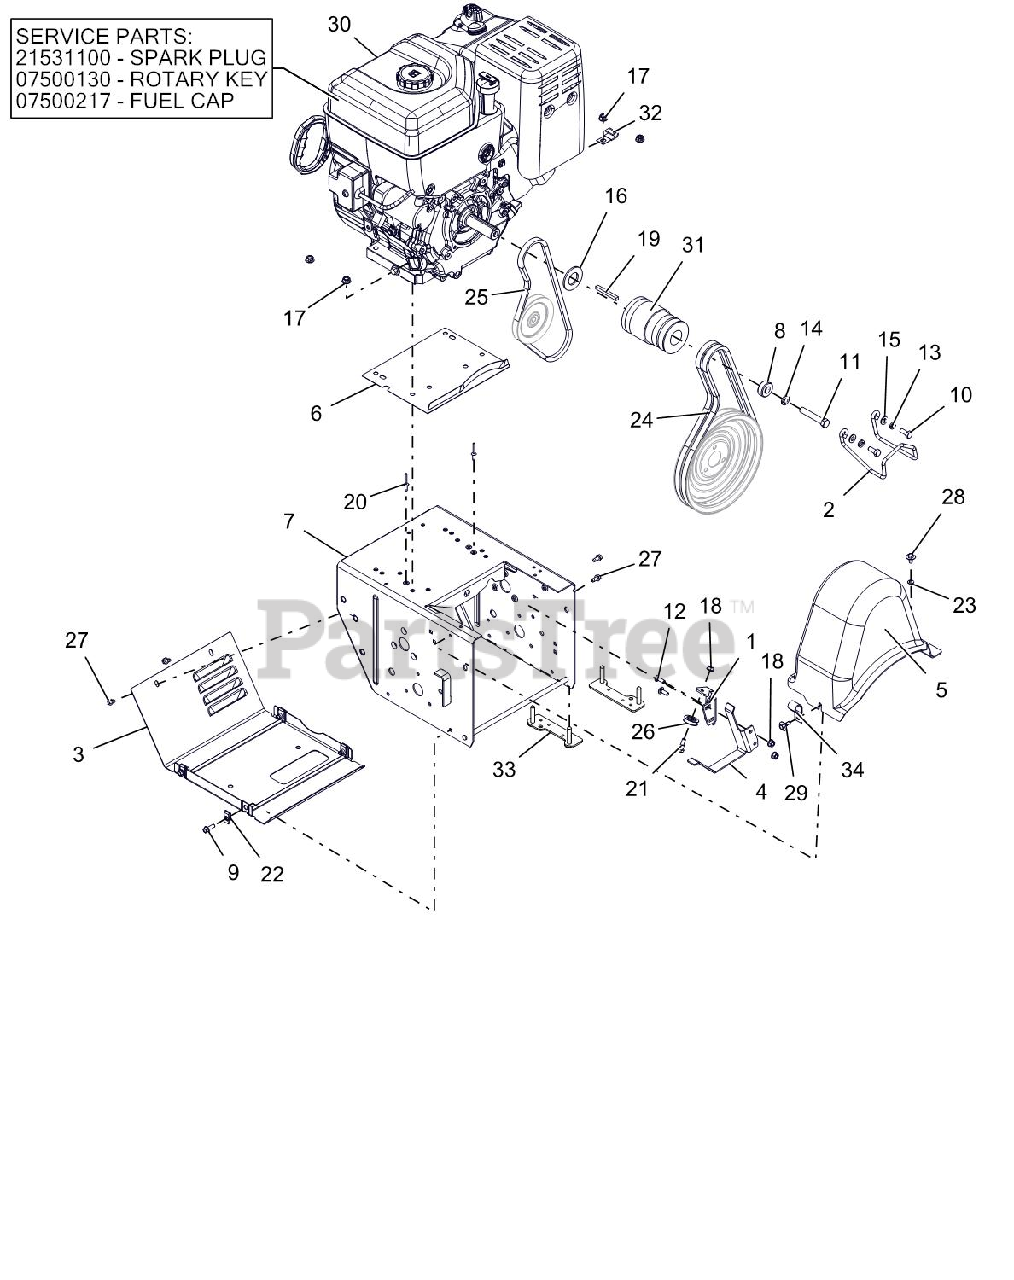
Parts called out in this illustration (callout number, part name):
1	BRACKET, CLUTCH CABLE
2	FINGER, BELT
3	COVER, BOTTOM - VENTILATED
4	FINGER, BELT - FLAT
5	COVER, BELT-LARGE
6	BAFFLE, WATER - LARGE BLOCK
7	FRAME, MAIN - PRO (WELDMENT)
8	BSHG-SPACER .47X1.25X.50
9	BLT-HEX .25-20X.75 HWH YZ GR5
10	BLT-HEX .31-24X.75 YWZC GR5
11	BLT-HEX .44-20X2.50 GR5 YWZC
12	@BLT-RDHDSQNK .25-20X.75 G5YZ
13	WSHR-LK .312X.097 HVY YWZC
14	@WSHR-LK .44X.109 REG YWZC
15	@WSHR-FL-STL.344X.688X.065YWZC
16	WSHR-FL-STL- 1.062X2.0X.134 YZ
17	@NUT-LK-CTR-FLG .31-18 YZ GR F
18	@NUT-LK-TOP-FLG .25-20 YWZC
19	KEY .25X.25X2.25
20	RVT-POP .187 YZ
21	BOLT, SHLDR-.375X.375X.25-20
22	NUT-RTNR .25-20X.56
23	NUT-PUSH .25X.50 O.D.
24	V-BELT, HA-RAW EDGE (SET)
25	V-BELT, 4L-WRAPPED
26	PULLEY, CABLE
27	SCR-TAP .25-20X.50 HWH TR YWZ
28	SCR-TAP .25-20X.50 LGHWH TR YZ
29	SCR-TAP .25-20X.5 CAPTIVE
30	PLUG, SPARK 20HP B&S VANGUARD
30	KEY, IGNITION ROTARY B&S
30	CAP, FUEL - BRIGGS & STRATTON
30	ENGINE, BRIGGS PF 2100, 12V
31	SHEAVE, COMBO HYDRO TRACK 4L
32	J-CLAMP
33	STRAP, BOLT-LARGE
34	J-CLAMP
